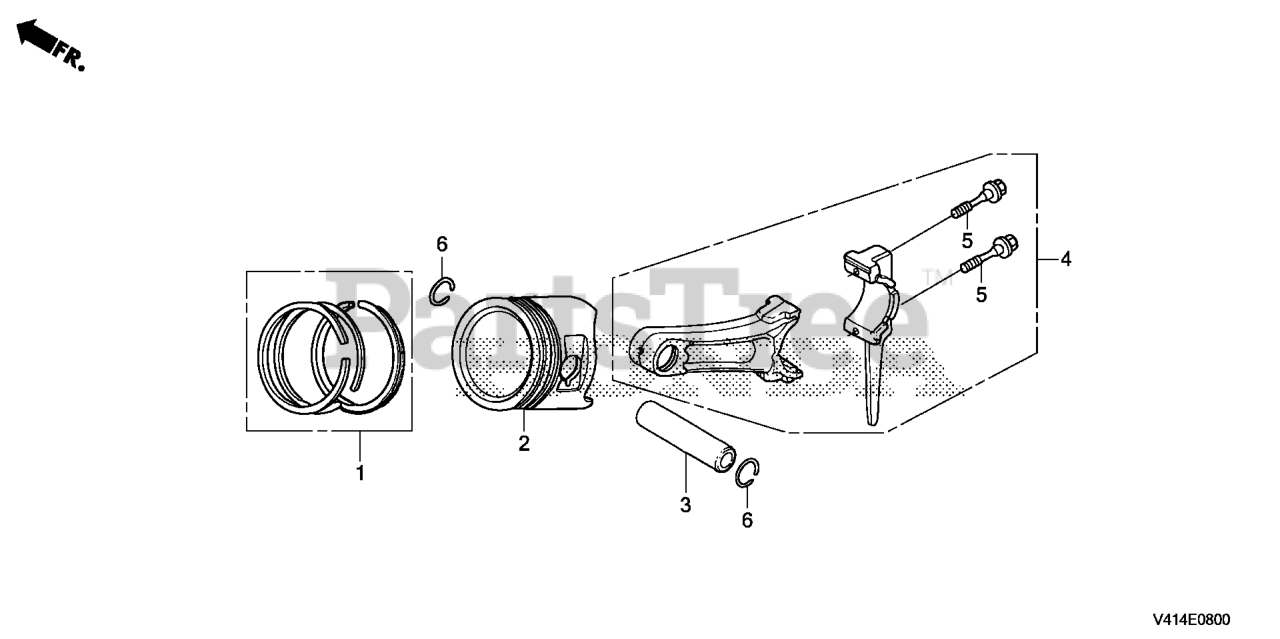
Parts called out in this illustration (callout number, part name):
1	RING SET, PISTON (STD) (TEIKOKU)
2	PISTON (STD)
3	PIN, PISTON
4	ROD ASSY., CONNECTING (STD)
5	BOLT, CONNECTING ROD
6	CLIP, PISTON PIN (20MM)
